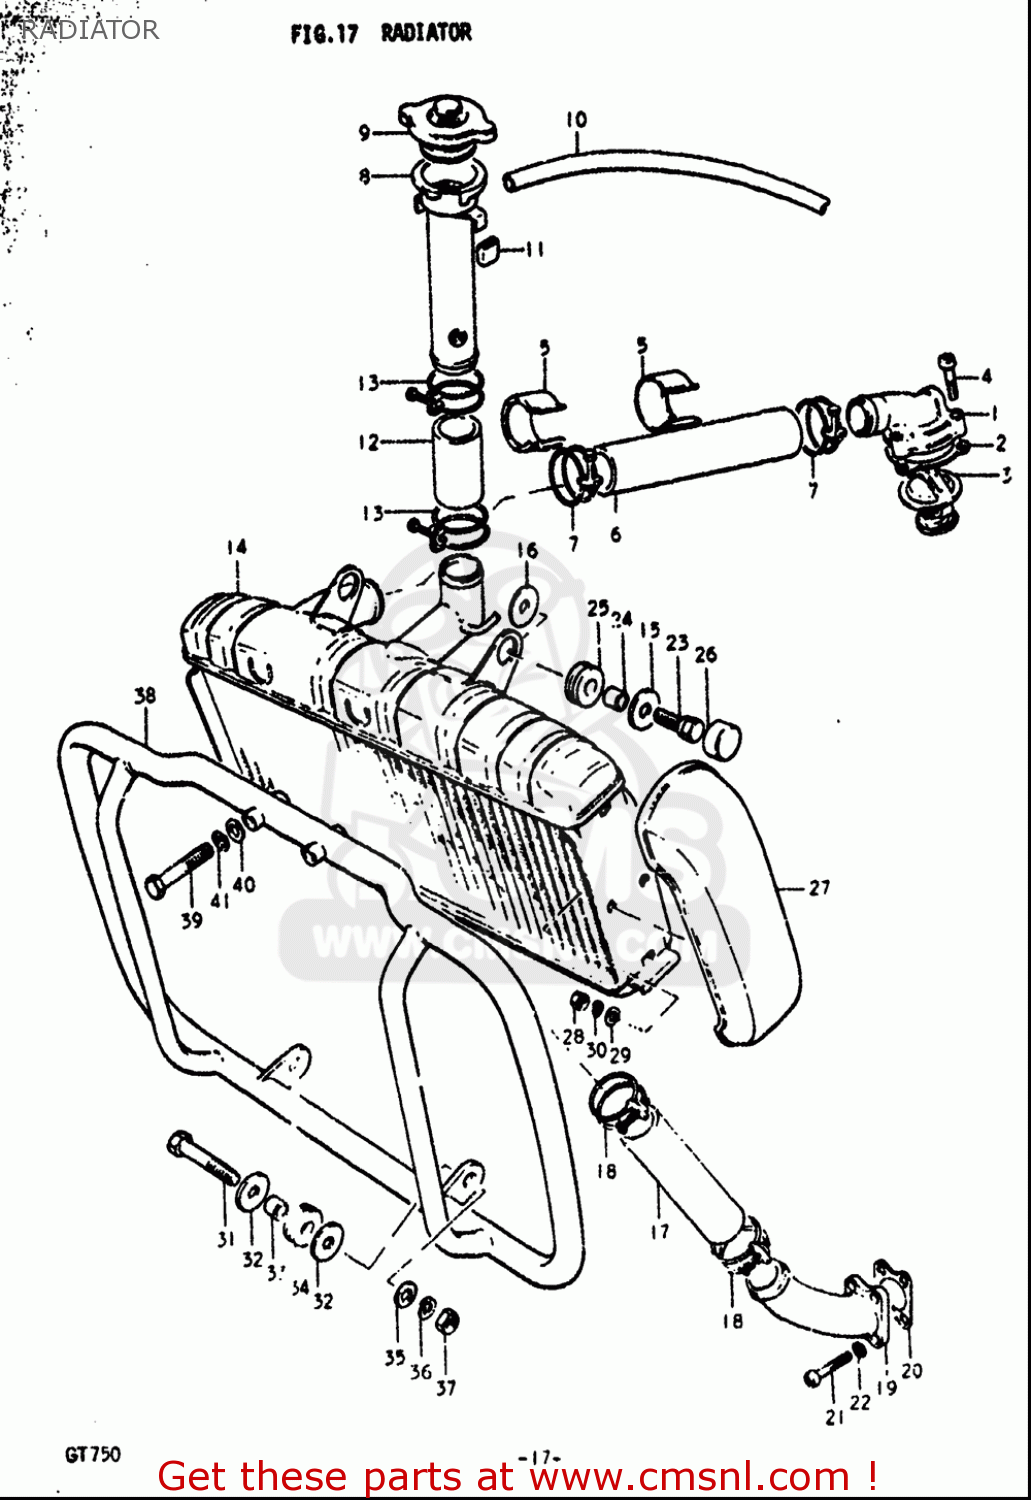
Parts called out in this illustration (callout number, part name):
2	GASKET,THERMOSTAT COVER (NAS)
3	THERMOSTAT,WATER
4	SCREW
6	HOSE(31X39X215)
7	CLAMP
9	CAP,RADIATOR 0.9
11	CUSHION
12	HOSE(31X39X215)
13	CLAMP
15	WASHER(8.5X28X1.6)
17	HOSE(31X39X215)
18	CLAMP
20	HOSE,WATER
21	SCREW
22	WASHER,LOCK
23	BOLT
24	SPACER,8.5X14X9
25	CUSHION
26	CUSHION
28	NUT
29	WASHER
30	WASHER,LOCK
31	BOLT
32	WASHER(8.5X28X1.6)
33	SPACER,8.5X14X9
34	CUSHION
35	WASHER
36	WASHER,LOCK
37	NUT
39	BOLT
40	WASHER
41	WASHER,LOCK
